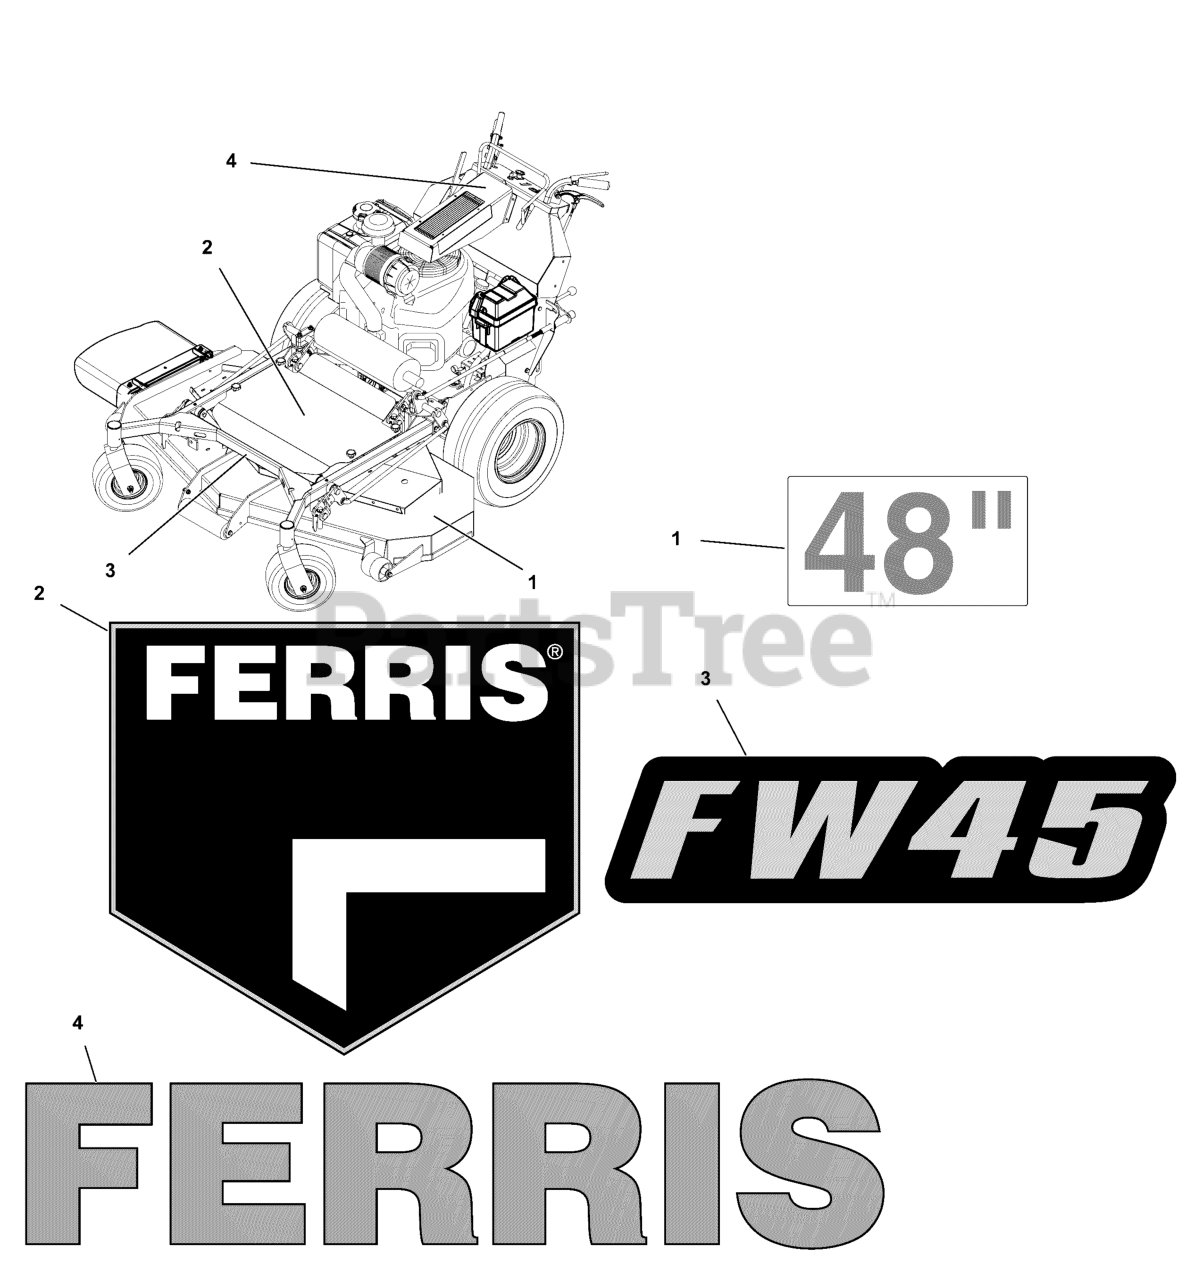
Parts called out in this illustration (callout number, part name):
1	DECAL, 48
2	DECAL, BRAND
3	DECAL, MODEL, W45
4	DECAL, FERRIS TEXT, 5"
